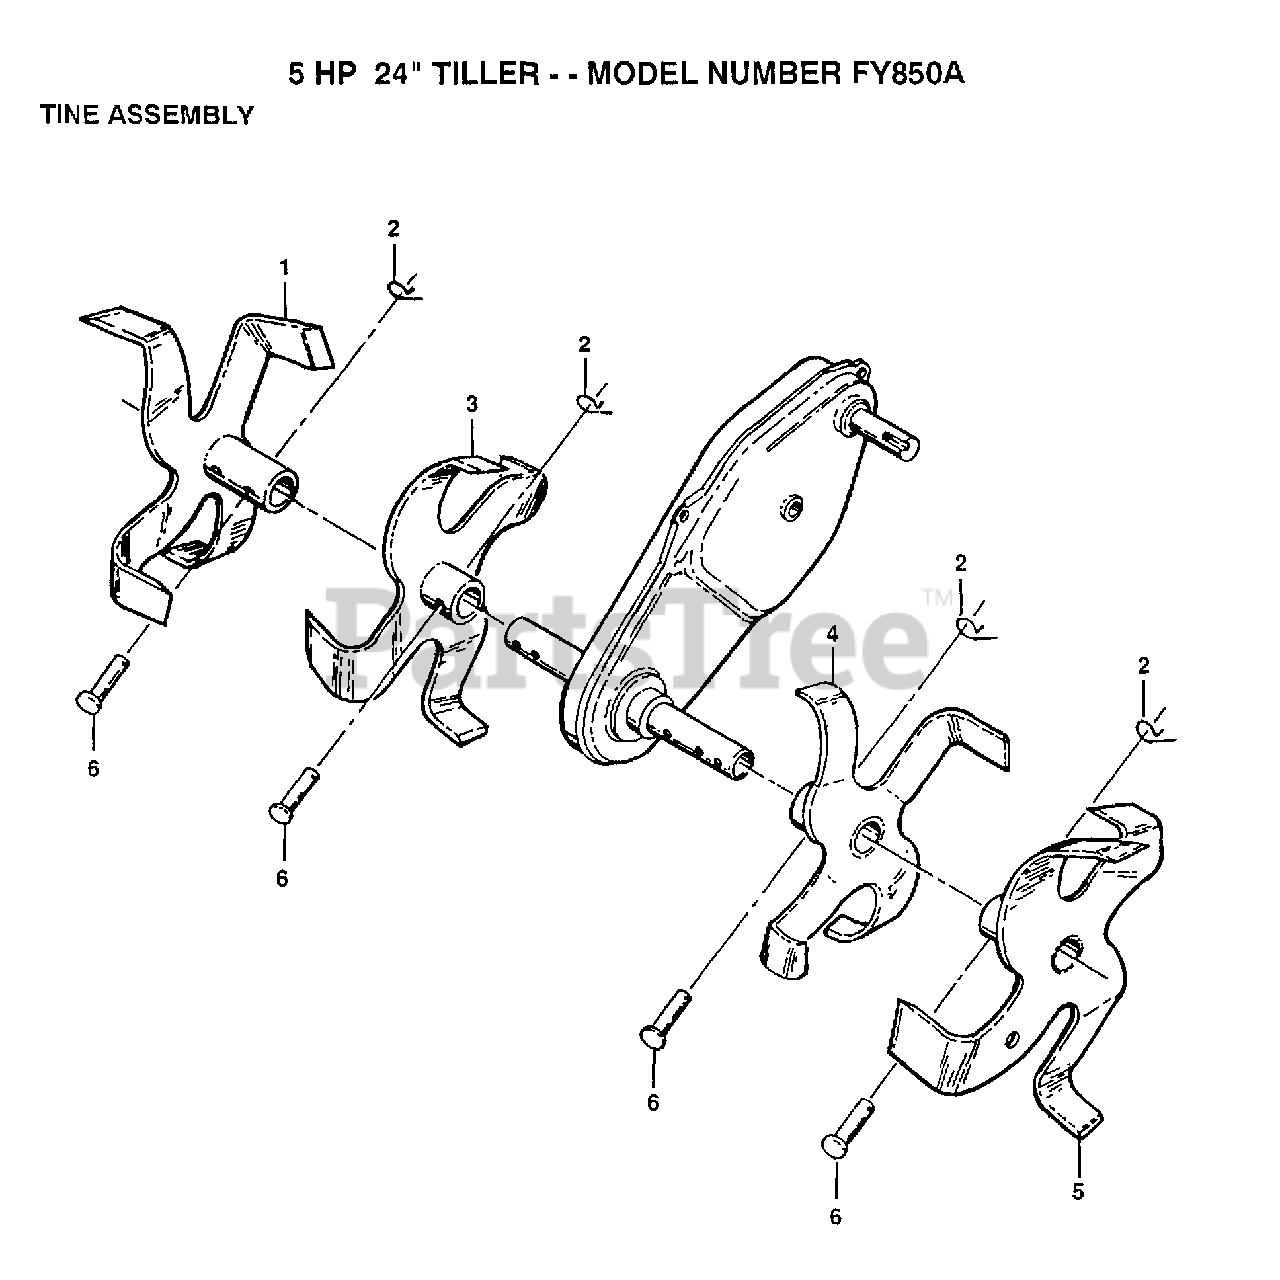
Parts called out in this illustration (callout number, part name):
1	TINE OUTER RH T
2	RETAINER.SPRING
4	TINE.INNER.LH
5	TINE.OUTER.LH.T
6	RIVET.PAN HD.1.75
